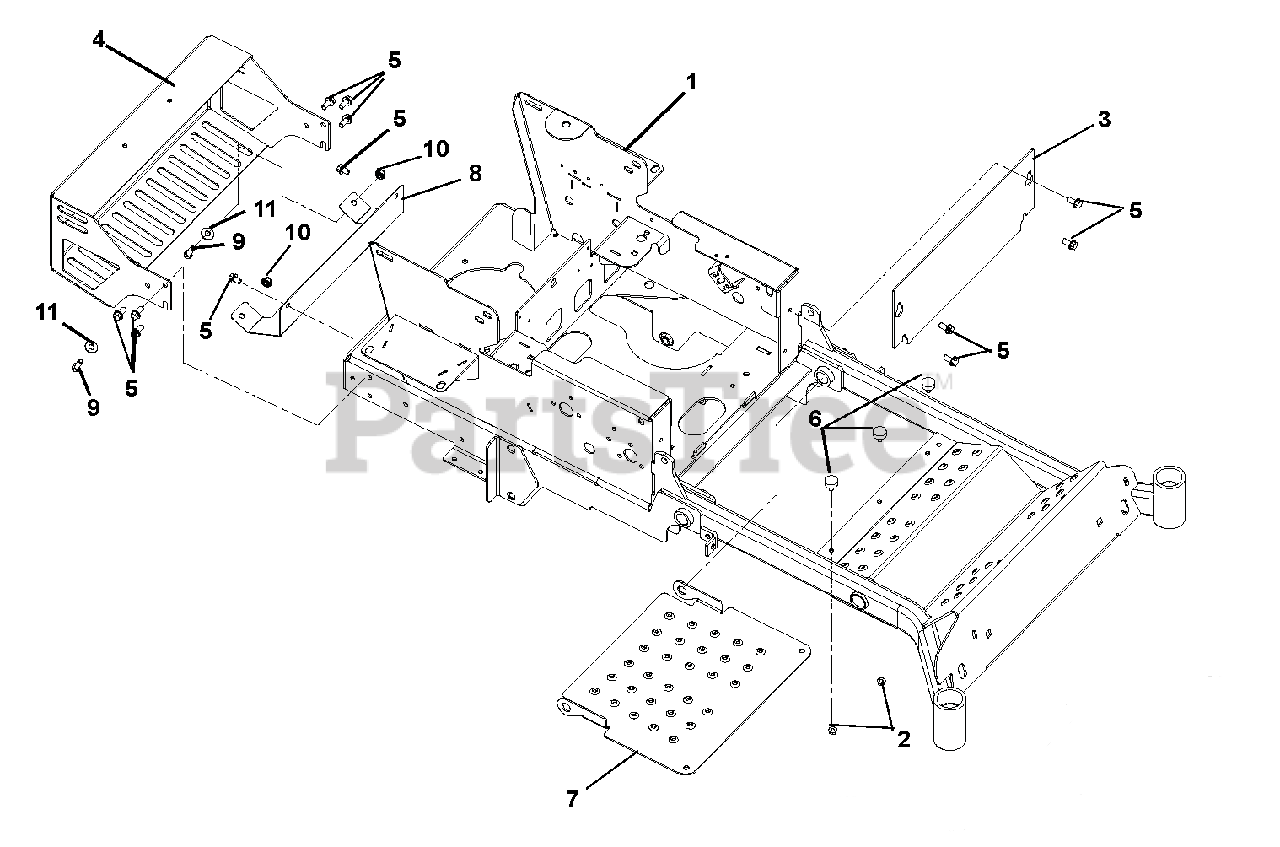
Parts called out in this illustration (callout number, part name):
1	ZOOM HD 52-60 MAIN FRM WMT-BLK
2	@NUT-SPNLK-FLG .312-18 YWZC
3	PLATE, KICK
4	ARIENS ZOOM HD BUMPER WMT -BLK
5	@SCR-TAP .38-16X.75 HWH TR YWZ
6	BUMPER, RUBBER
7	PANEL, INSPECTION
8	SHIELD - HEAT - CZ PROD
9	@BLT-HEX .38-16X1.00 GR5 YWZC
10	@NUT-LK-NYL-FLG .38-16 YWZC
11	@WSHR-FL-STL.438X1.00X.083 YWZ
